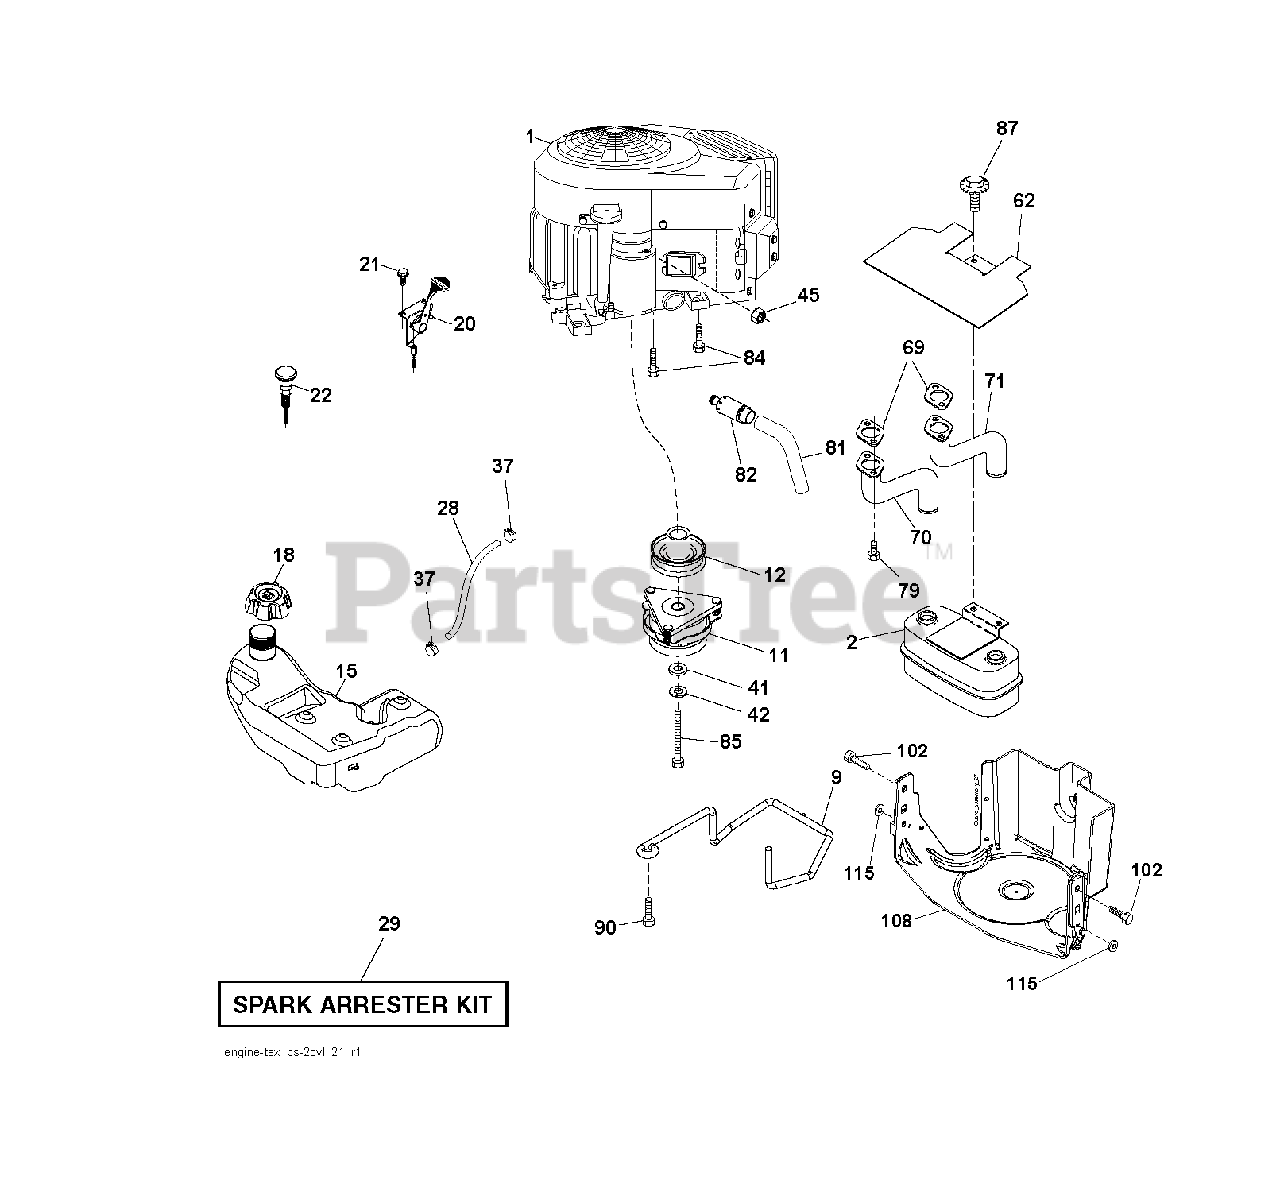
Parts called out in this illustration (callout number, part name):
2	MUFFLER.TWIN.CYL.LOW.TONE
9	KEEPER.BELT.ENGINE.4.2
11	CLUTCH ELECTRIC
12	PULLEY ENGINE
15	TANK.FUEL.4GAL
18	CAP.ASM.FUEL.TANK.3"BL
20	THROTTLE CABLE
21	SCREW.#10 X 0.750.BOS THREAD
22	CONTROL CHOKE
28	LINE.FUEL.20
29	ARRESTER SPARK (OPTIONAL)
37	HOSE CLAMP
42	LOCKWASHER
45	NUT
62	RP SHIELD HEAT MUFFLER
69	GASKET.MUFFLER
70	TUBE MANIFOLD LH
71	EXHAUST TUBE RH
79	SCREW.SOCKET.HEAD.5/16-18
81	TUBE, DRAIN OIL ASM.
82	PLUG DRAIN OIL EASY
84	SCREW.3/8-16
85	BOLT HEX 7/16-20 X 3.75 GR. 5
87	BOLT, 5/16-18 X 1 3/4
90	SCREW 3/8-16X1
102	SCREW
